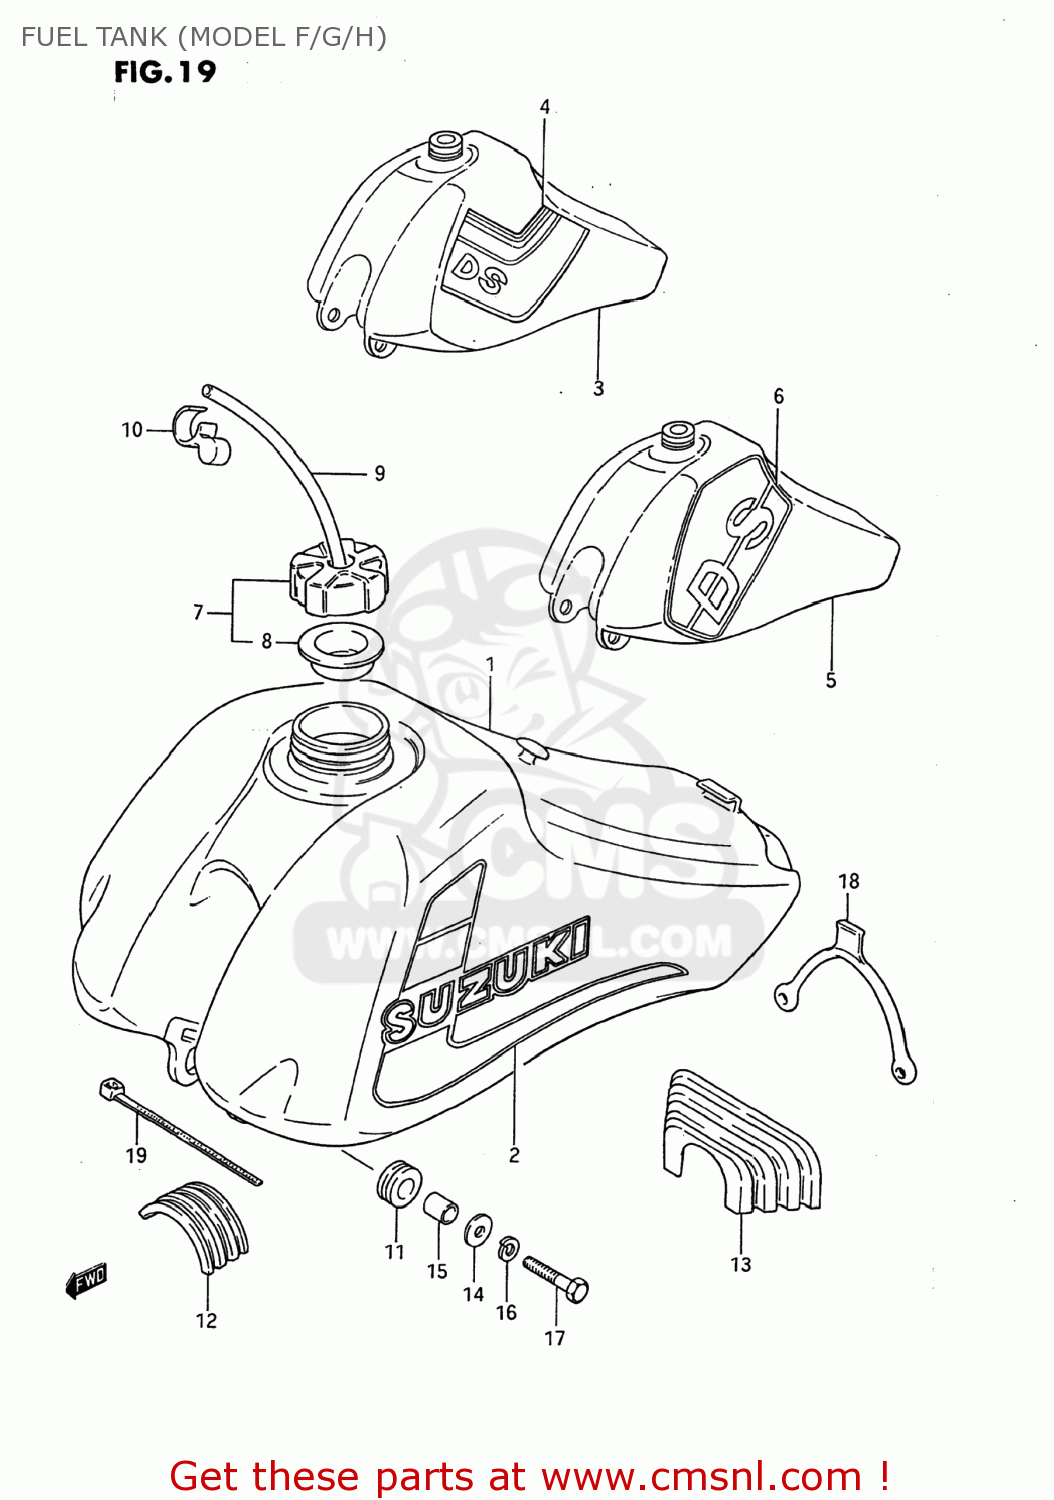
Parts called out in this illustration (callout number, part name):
1	TANK ASSEMBLY,FUEL
2	TAPE SET,FUEL TANK
3	TANK ASSEMBLY,FUEL
4	TAPE SET,FUEL TANK
5	TANK ASSEMBLY,FUEL
6	TAPE SET,FUEL TANK
7	CAP SET,FUEL TANK
8	GASKET,FUEL TANK CAP (NAS)
9	HOSE(5X8.2X600)
10	CLAMP
11	CUSHION
12	CUSHION,FUEL TANK UPR FR
13	CUSHION,FUEL TANK UPR RR
14	WASHER (6.5X24X1.6)
15	SPACER (6.5X10.5X13.5)
16	WASHER,LOCK
17	BOLT
18	BAND,FUEL TANK RR
19	CLAMP
